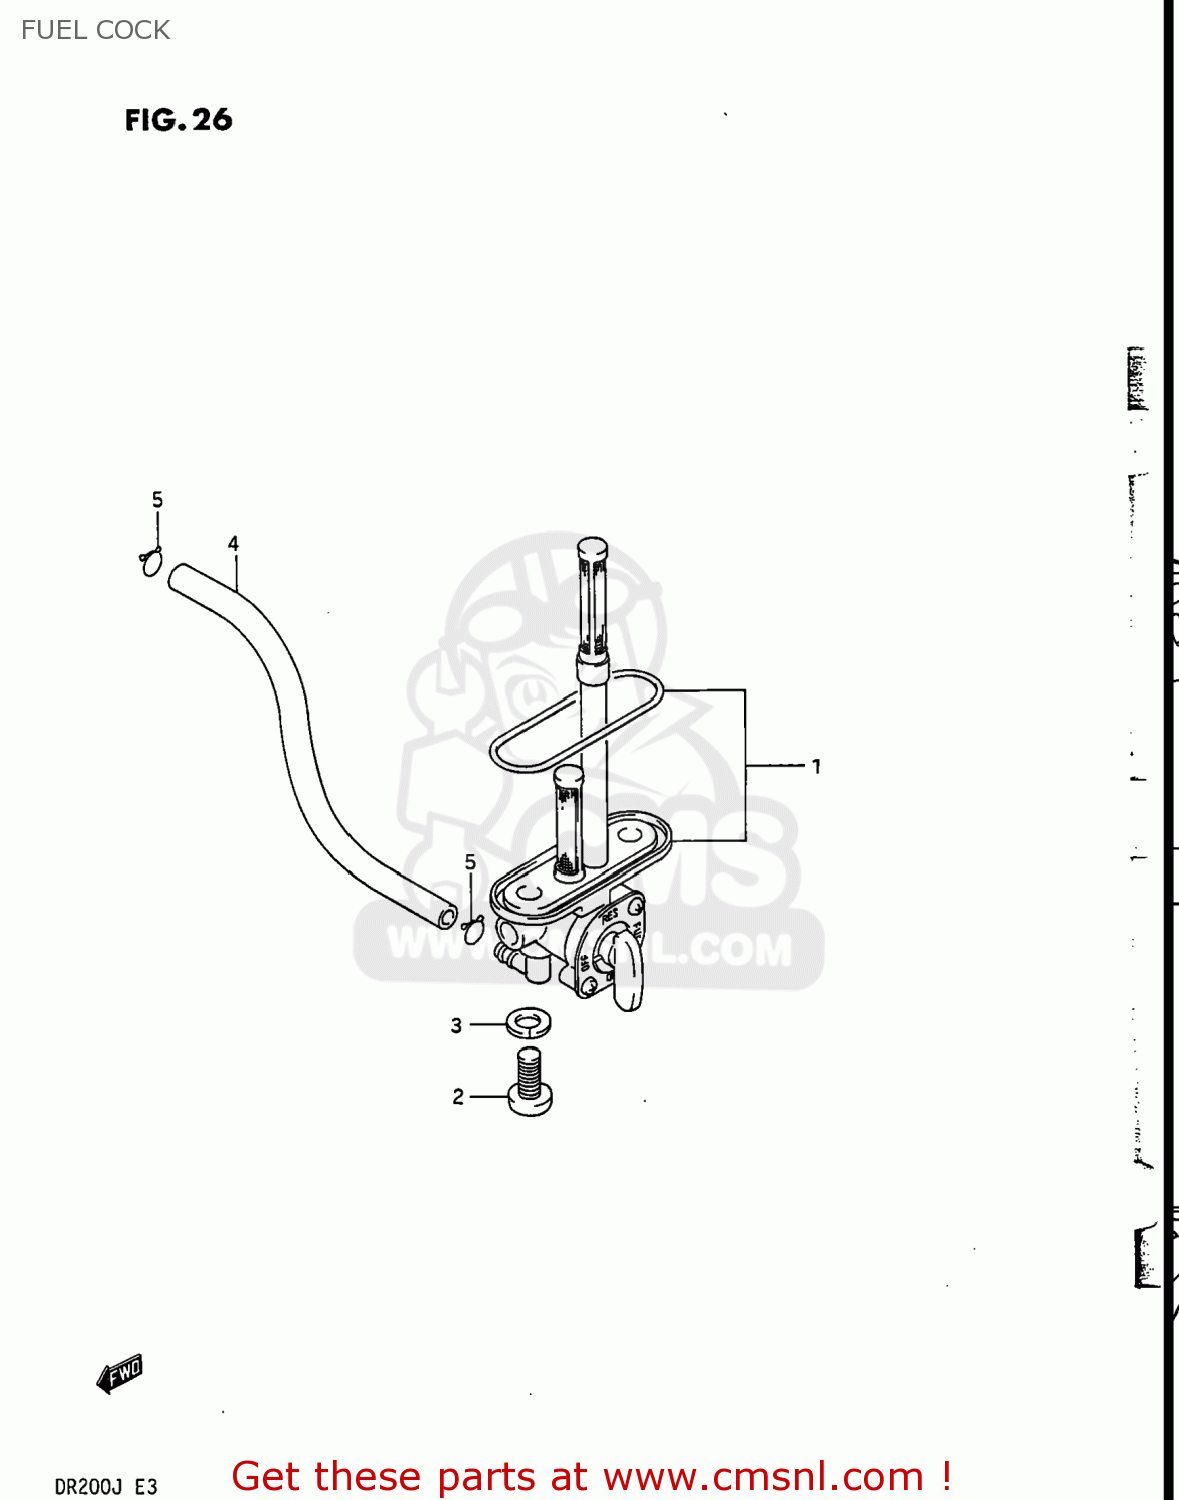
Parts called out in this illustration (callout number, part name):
1	COCK ASSY,FUEL
2	SCREW
3	WASHER,LOCK
4	HOSE
5	CLIP
